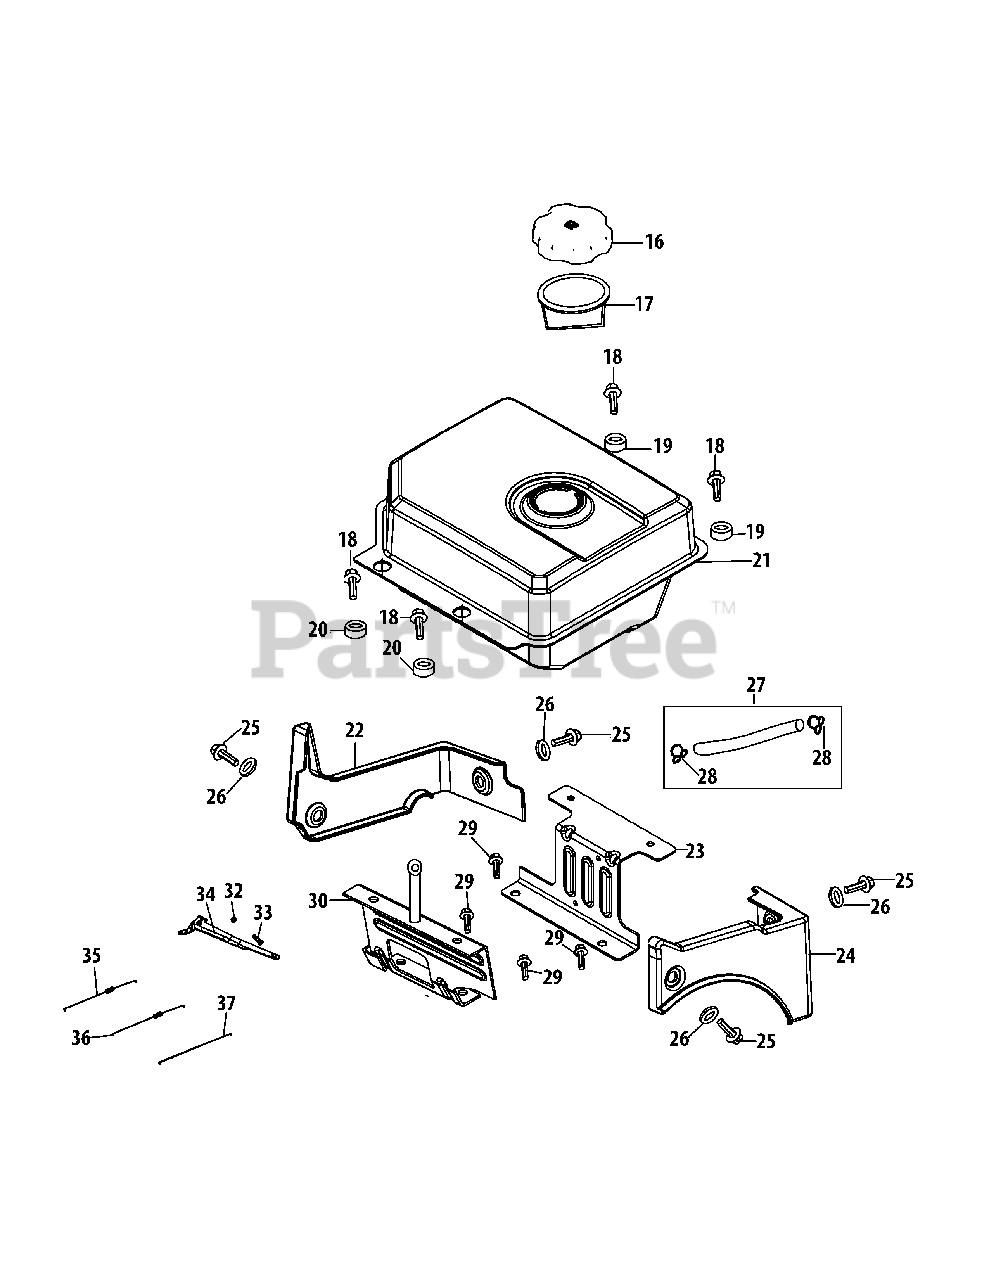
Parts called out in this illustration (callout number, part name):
16	Fuel Cap Assembly
17	Fuel Level Indicator
18	Bolt M8×20
19	Bushing, Slot
20	Bushing, Rnd
21	Fuel Tank Assembly
22	Fuel Tank Shroud
23	Fuel Tank Mounting Bracket
24	Engine Shroud
25	Bolt M6×16
27	Fuel Line Kit
28	Fuel Hose Clamp
29	Bolt M8×14
30	Fuel Tank Mounting Bracket
32	Flange Nut M6
33	Governor Arm Bolt M6X21
34	Governor Arm
35	Governor Spring
36	Throttle Return Spring
37	Governor Rod
